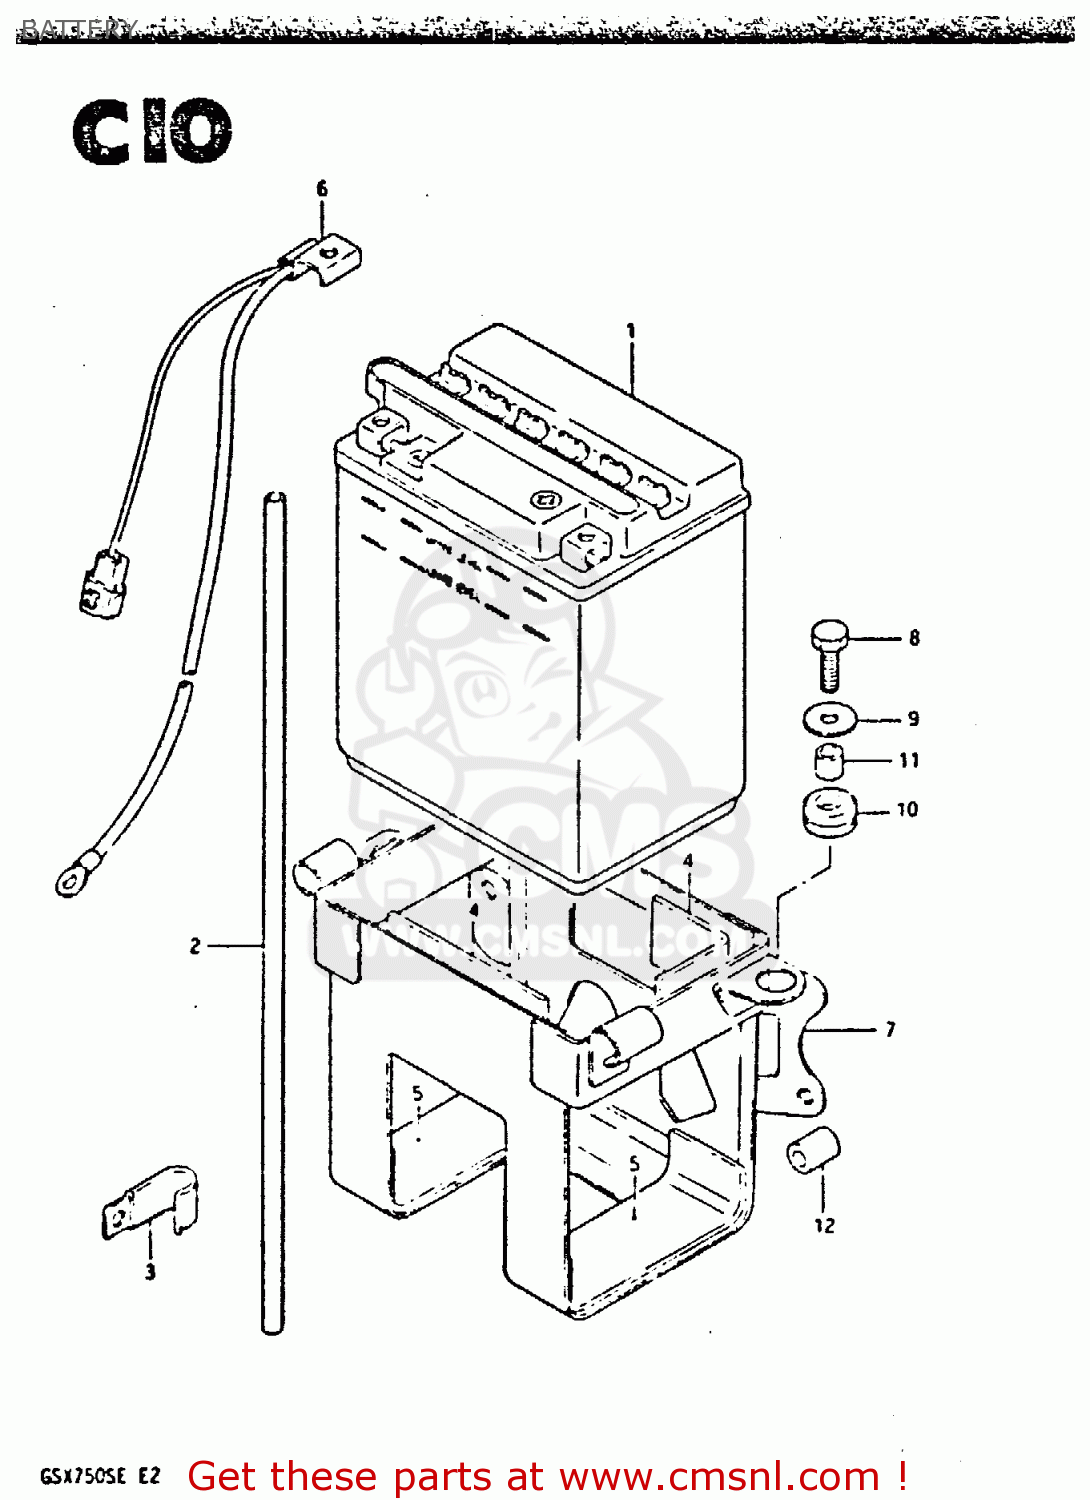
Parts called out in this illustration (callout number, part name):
1	BATTERY ASSY (12V)
2	HOSE,BATTERY EXHAUST
3	CLAMP
4	PROTECTOR(30X80X2)
5	PROTECTOR(170X95X3.0)
6	LEAD WIRE, (-)
7	HOLDER, BATTERY
8	SCREW
9	WASHER (6.5X20X1.2)
10	CUSHION
11	SPACER(6.1X9X7.5)
12	CUSHION
